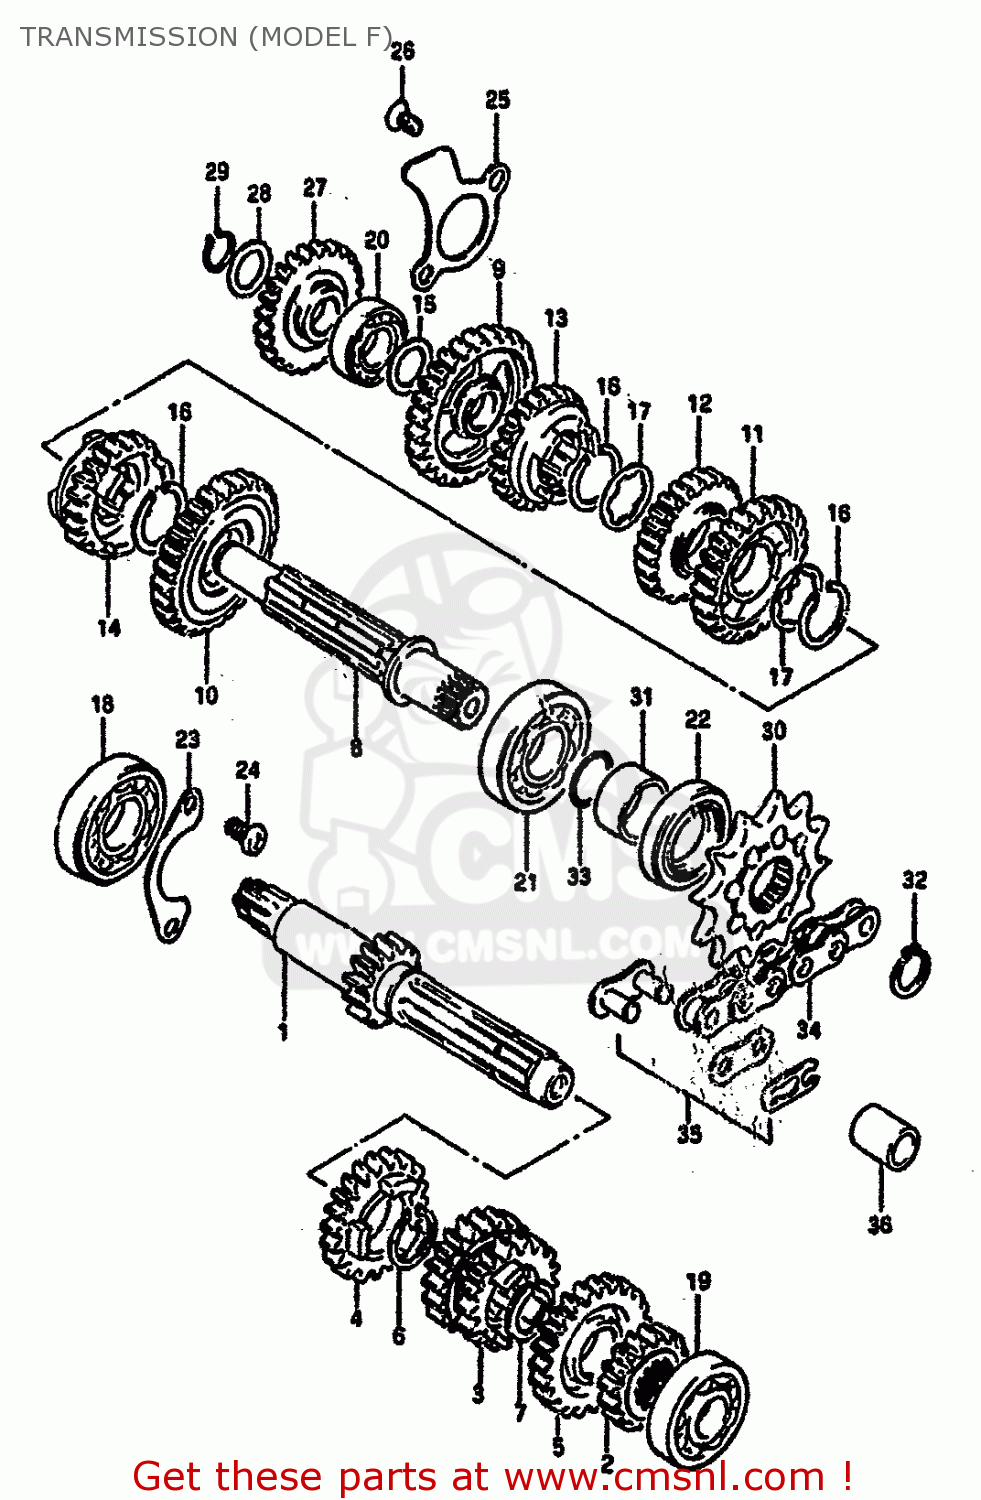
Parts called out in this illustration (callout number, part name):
1	SHAFT,COUNTER
2	GEAR,SECOND DRIVE
3	GEAR,THIRD/FOURTH DRIVE
4	GEAR,FIFTH DRIVE
5	GEAR,SIXTH DRIVE
6	CIRCLIP
7	CIRCLIP
8	SHAFT,DRIVE
9	GEAR,FIRST DRIVEN
10	GEAR,SECOND DRIVEN
11	GEAR,THIRD DRIVEN
12	GEAR,FOURTH DRIVEN
13	GEAR,FIFTH DRIVEN
14	GEAR,SIXTH DRIVEN
15	WASHER,THRUST
16	CIRCLIP
17	WASHER,LOCK
18	BEARING
19	BEARING
20	BEARING
21	BEARING(20X47X14)
22	SEAL,OIL(25X40X7)
23	RETAINER,CNTR SHAFT BEARING
24	SCREW 6X12
25	RETAINER,DRIVESHAFT
26	SCREW
27	GEAR,KICK STARTER IDLE
28	WASHER,THRUST
29	CIRCLIP,15MM
30	SPROCKET,ENGINE
31	SPACER(20X25X12.5)
32	CIRCLIP
33	O RING(D:1,ID:19.5)
34	CHAIN ASSEMBLY,DRIVE
35	JOINT ASSEMBLY,CHAIN
36	CUSHION 12X20X20
